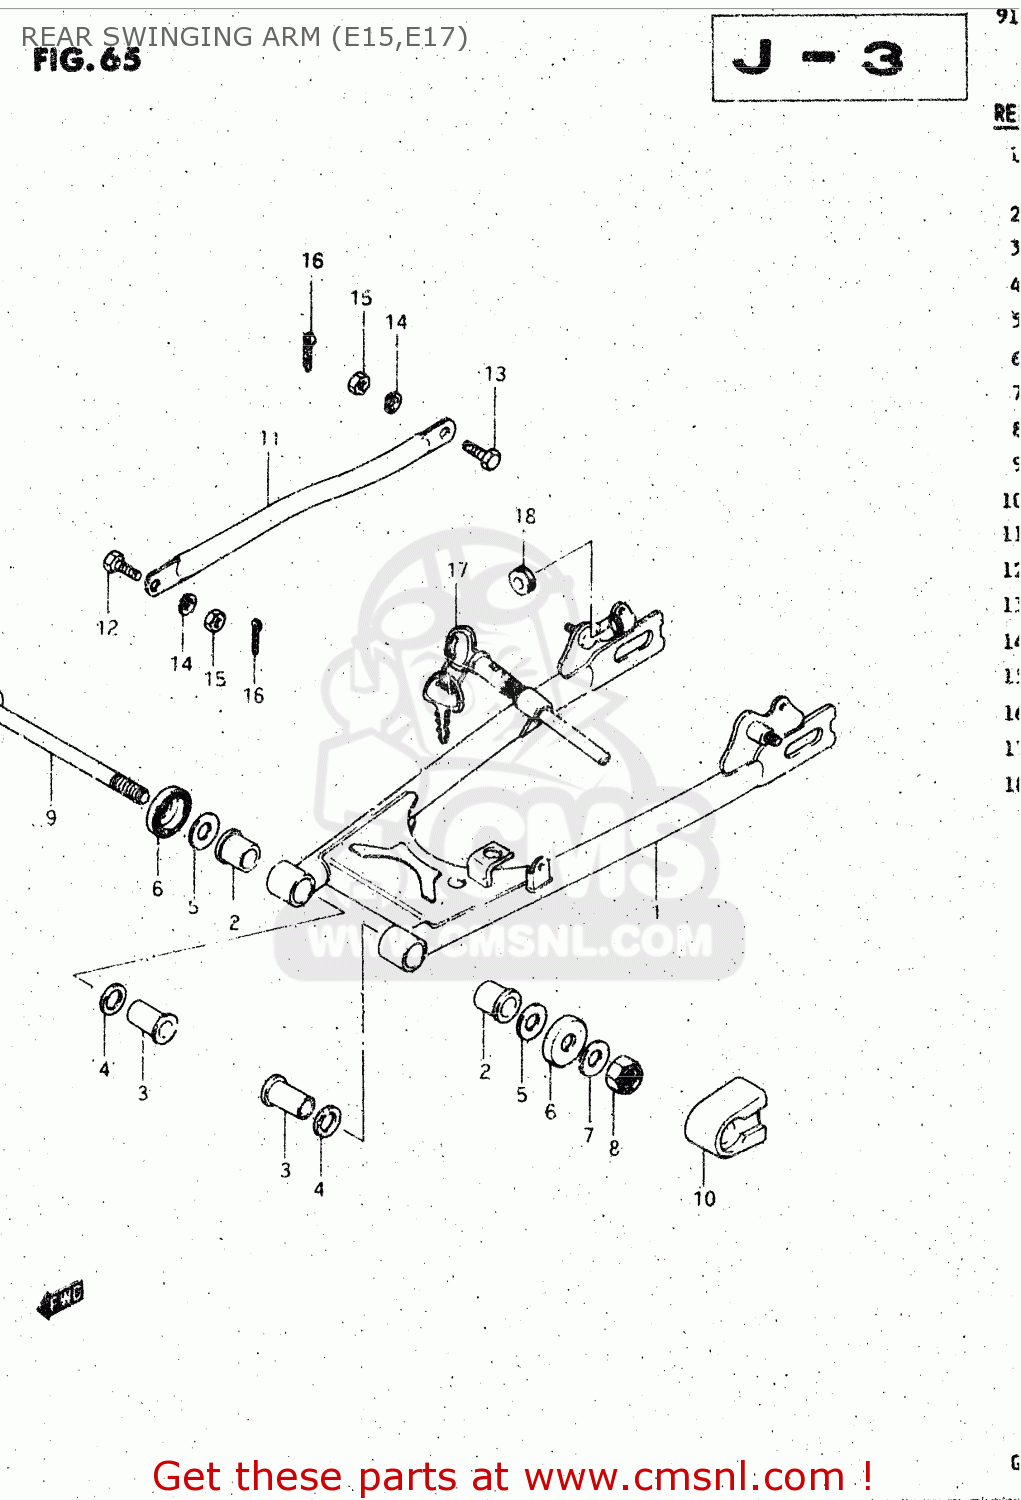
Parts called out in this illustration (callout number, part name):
1	SWINGING ARM ASSY, REAR (BLACK)
2	BUSH,RR SWINGING ARM PIVOT
3	SPACER,RR SWGARM PIVOT
4	SEAL,OIL(20X27X5)
5	WASHER
6	CVR,RR SWGARM DUST SEAL(OD:40)
7	WASHER
8	NUT 14MM
9	SHAFT,REAR SWING ARM
10	BUFFER,CHAIN TOUCH DEFENSE
11	TORQUELINK,RR
12	BOLT(8X22.5)
13	BOLT(8X26.5)
14	WASHER,LOCK
15	NUT
16	PIN 20X20
17	LOCK SET, WHEEL
18	CUSHION
